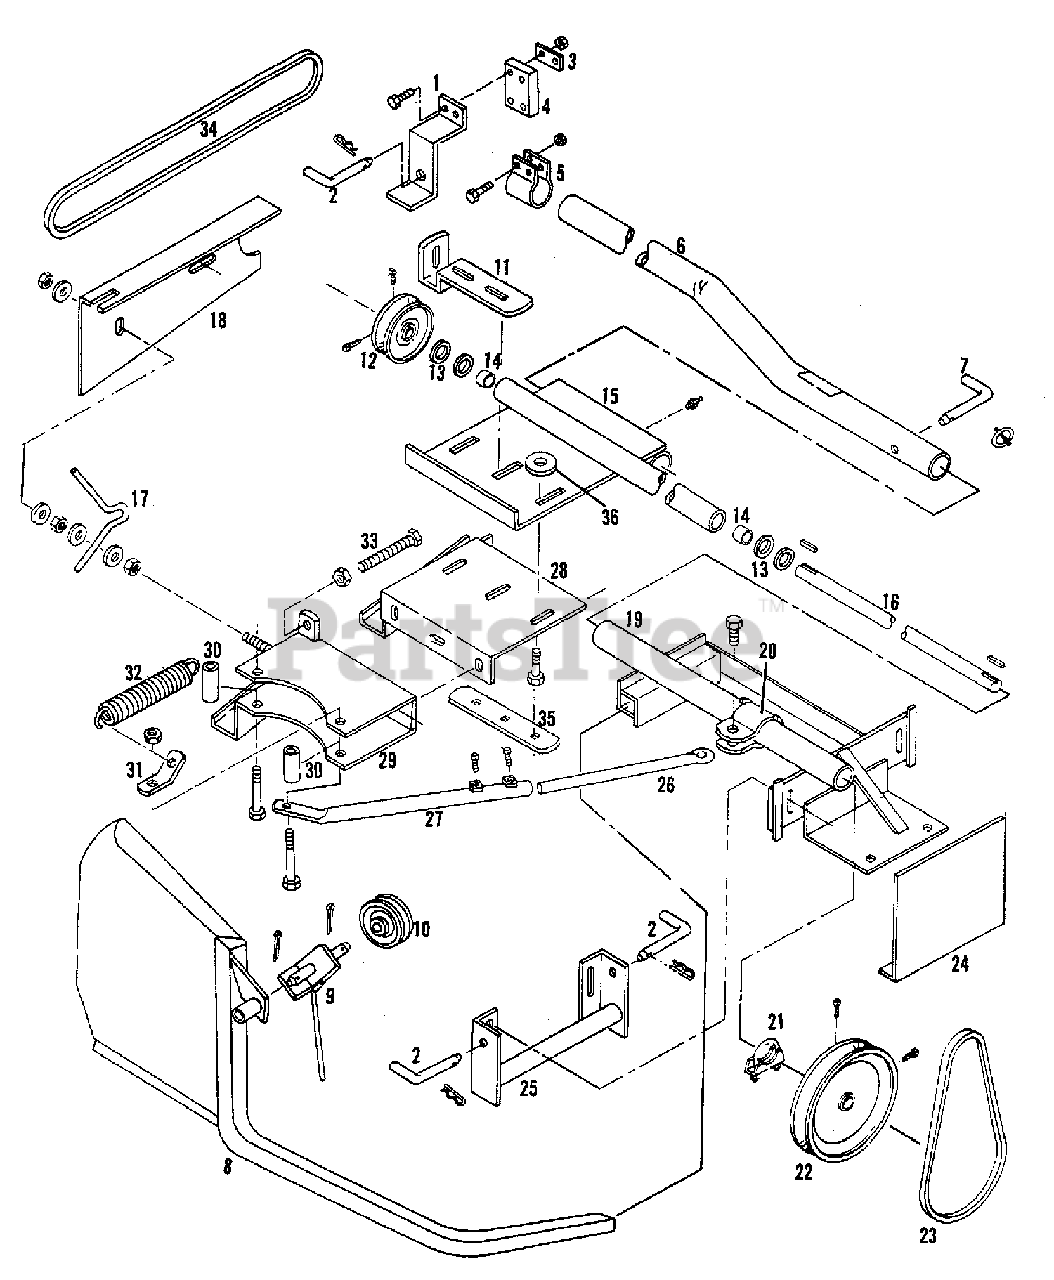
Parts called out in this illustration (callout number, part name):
1	BAR ASSEMBLY, Hitch
1	CAPSCREW, 1/4NC x 1-1/4
1	NUT, 1/4NC - Lock
2	PIN, Locating
2	PIN, Quick
3	STRAP, Clamp
4	BLOCK, Rubber
5	CAPSCREW, 1/4NC x 1-1/4
5	NUT, 1/4NC - Lock
6	PIPE, Pivot
7	PIN, Hitch
7	PIN, Quick Clip
8	FRAME ASSEMBLY, Carrier
9	BRACKET ASSEMBLY, Pulley Mount
9	PIN, 1/8 x 2 (Cut To 1-1/4)
10	PULLEY, Lift
11	BRACKET, Guard Mount
12	PULLEY, 3-1/2" O.D.
12	SETSCREW, 5/16NC x 1/2, Square Head, Cup Point
13	WASHER, 3/4 Plain
14	BEARING, Housing
15	BRACKET ASSEMBLY, Pivot
15	FITTING, 1/4NF - Lube (Package Of 10)
16	SHAFT, Jack (Main Drive)
16	KEY, 3/16 Square x 1
17	RETAINER, Belt
17	WASHER, 1/2 x 1-1/4
17	NUT, 1/2NC
18	GUARD, Belt
18	WASHER, 2-3/8
18	CAPSCREW, 3/8NC x 3/4
18	NUT, 3/8NC
19	FRAME ASSEMBLY, Front Hanger
19	CAPSCREW, 3/8NC x 1
19	LOCKWASHER, 3/8
20	CLAMP, Sleeve
20	CAPSCREW, 1/2NC x 1-1/4
20	NUT, 1/2NC - Lock
21	U-BOLT ASSEMBLY
22	PULLEY, 7" O.D.
22	SETSCREW, 5/16NC x 1/2, Square Head, Cup Point
23	BELT, Engine To Jackshaft
24	GUARD, Pulley
25	BRACKET ASSEMBLY, Hanger Mounting
25	BOLT, 1/2NC x 1-1/4 Carriage
25	LOCKWASHER, 1/2
25	NUT, 1/2NC
26	ROD, Stabilizer
27	ROD ASSEMBLY, Stabilizer Extension
27	SETSCREW, 3/8NC x 3/4, Square Head Cup Point
27	CAPSCREW, 1/2NC x 3-1/2
27	LOCKWASHER, 1/2
27	NUT, 1/2NC
28	PLATE ASSEMBLY, Carrier Adjust
29	HOUSING, Breakaway
29	BOLT, 1/2NC x 1-1/4 Carriage
29	WASHER, 1/2
30	CAPSCREW, 1/2NC x 3-1/2
30	CAPSCREW, 1/2NC x 3
31	ANCHOR, Spring
33	CAPSCREW, 1/2NC x 4, Anchor
33	NUT, 1/2NC
34	BELT, Jackshaft To Sickle
35	BOLT, 1/2NC x 1-1/2, Carriage
36	WASHER, 1-3/4
